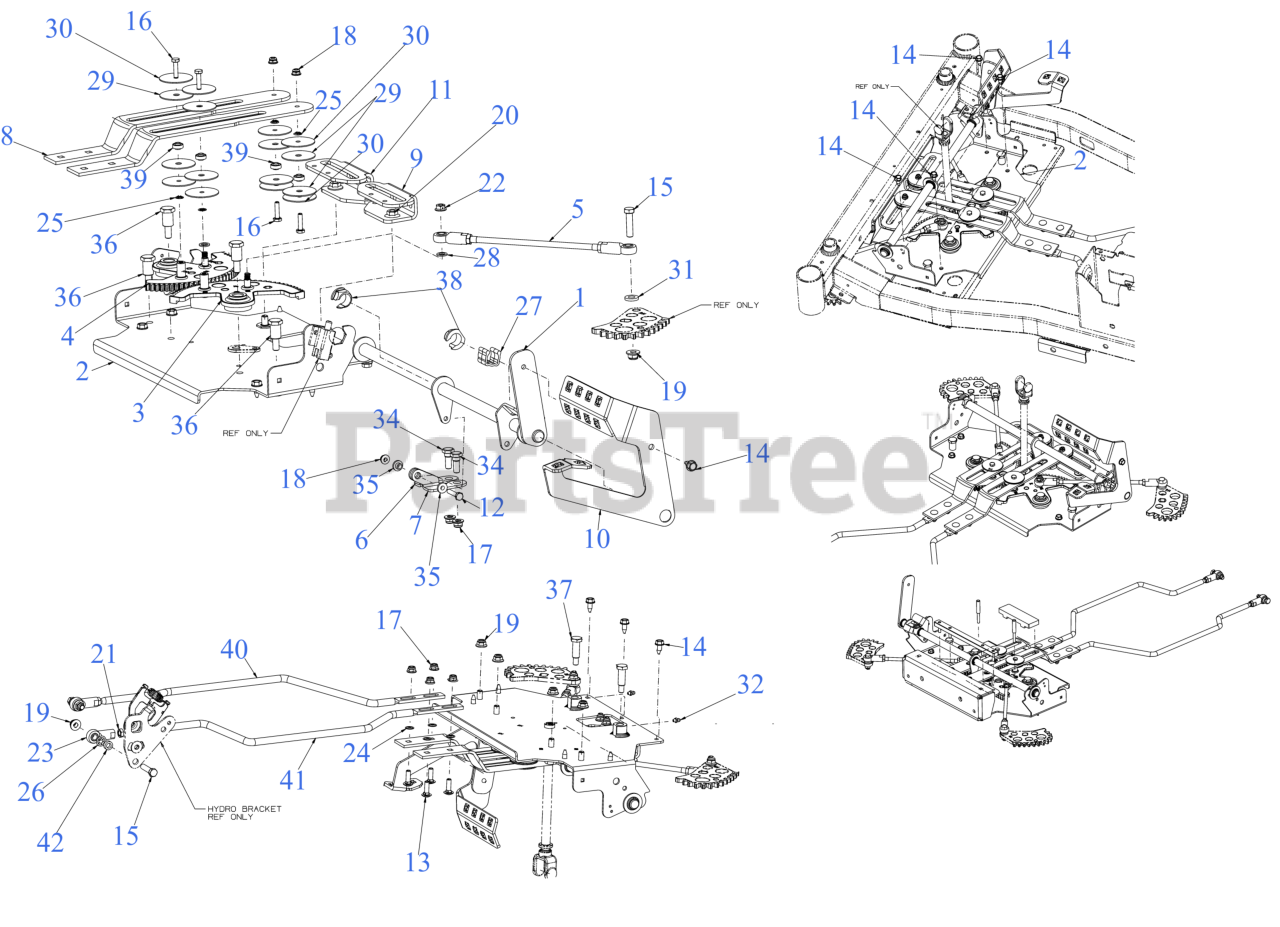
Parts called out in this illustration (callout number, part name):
1	DRIVE PEDAL SHAFT
2	STEERING SUPPORT PLATE
3	STEERING GEAR ASSEMBLY (RH)
3	FLANGE BUSHING
4	STEERING GEAR ASSEMBLY (LH)
4	FLANGE BUSHING
5	STEERING TIE ROD
5	BALL JOINT
5	HEX JAM NUT 3/8X24
7	PEDAL SHAFT BRACKET (RH)
8	CONTROL LINK
9	SPEED CAM PLATE (RH)
10	FWD/REV PEDAL
11	SPEED CAM PLATE (LH)
12	HEX SCREW 1/4-20 x 1.25
13	CARRIAGE BOLT 5/16-18 x 1.00
14	SCREW 5/16-18 x .750
15	SCREW 3/8-16 x 1.50
16	SCREW 1/4-20X1.0 GR5
17	FLANGE LOCK NUT 5/16-18
18	FLANGE LOCK NUT
20	FLANGE LOCK NUT
21	HEX JAM NUT 3/8X24
22	HEX FLANGE NUT
23	BALL JOINT
25	RETAINER-BOLT .25ID x .50OD
26	SPEED NUT
27	SPACER-LIFT SHAFT
28	FLAT WASHER
29	FLAT WASHER
30	FLAT WASHER
31	FLAT WASHER
32	GREASE ZERT 1/4-28
34	SHOULDER SCREW .437
35	SHOULDER SPACER
36	SHOULDER SCREW .625 x .875 x 3/18
37	SHOULDER SCREW .50
38	HEX FLANGE SPLIT BEARING
39	BALL BEARING .25 x .625
40	HYDRO LINK ROD (RH)
41	HYDRO LINK ROD (LH)
42	SPACER-.380 ID x .625 OD x .227
